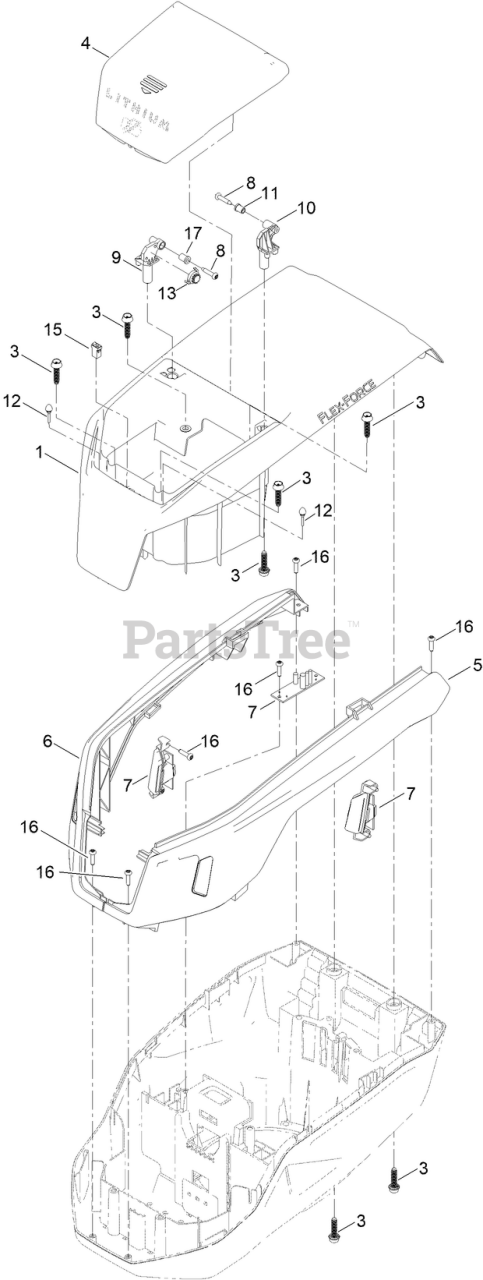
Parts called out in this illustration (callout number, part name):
1	SHROUD-UPPER
3	SCREW-FLANGE, PLASTIC
4	DOOR-BATTERY
5	BEZEL-LH
6	BEZEL-RH
7	LED ASM
9	PIVOT-DOOR, BATTERY
10	PIVOT-DOOR, BATTERY
11	BUSHING-SPACER
12	BUMPER-RUBBER
13	DAMPER-GEAR
15	LATCH-PUSH
16	SCREW-TORX DRIVE PLASTITE
17	BUSHING-SPACER, METAL
